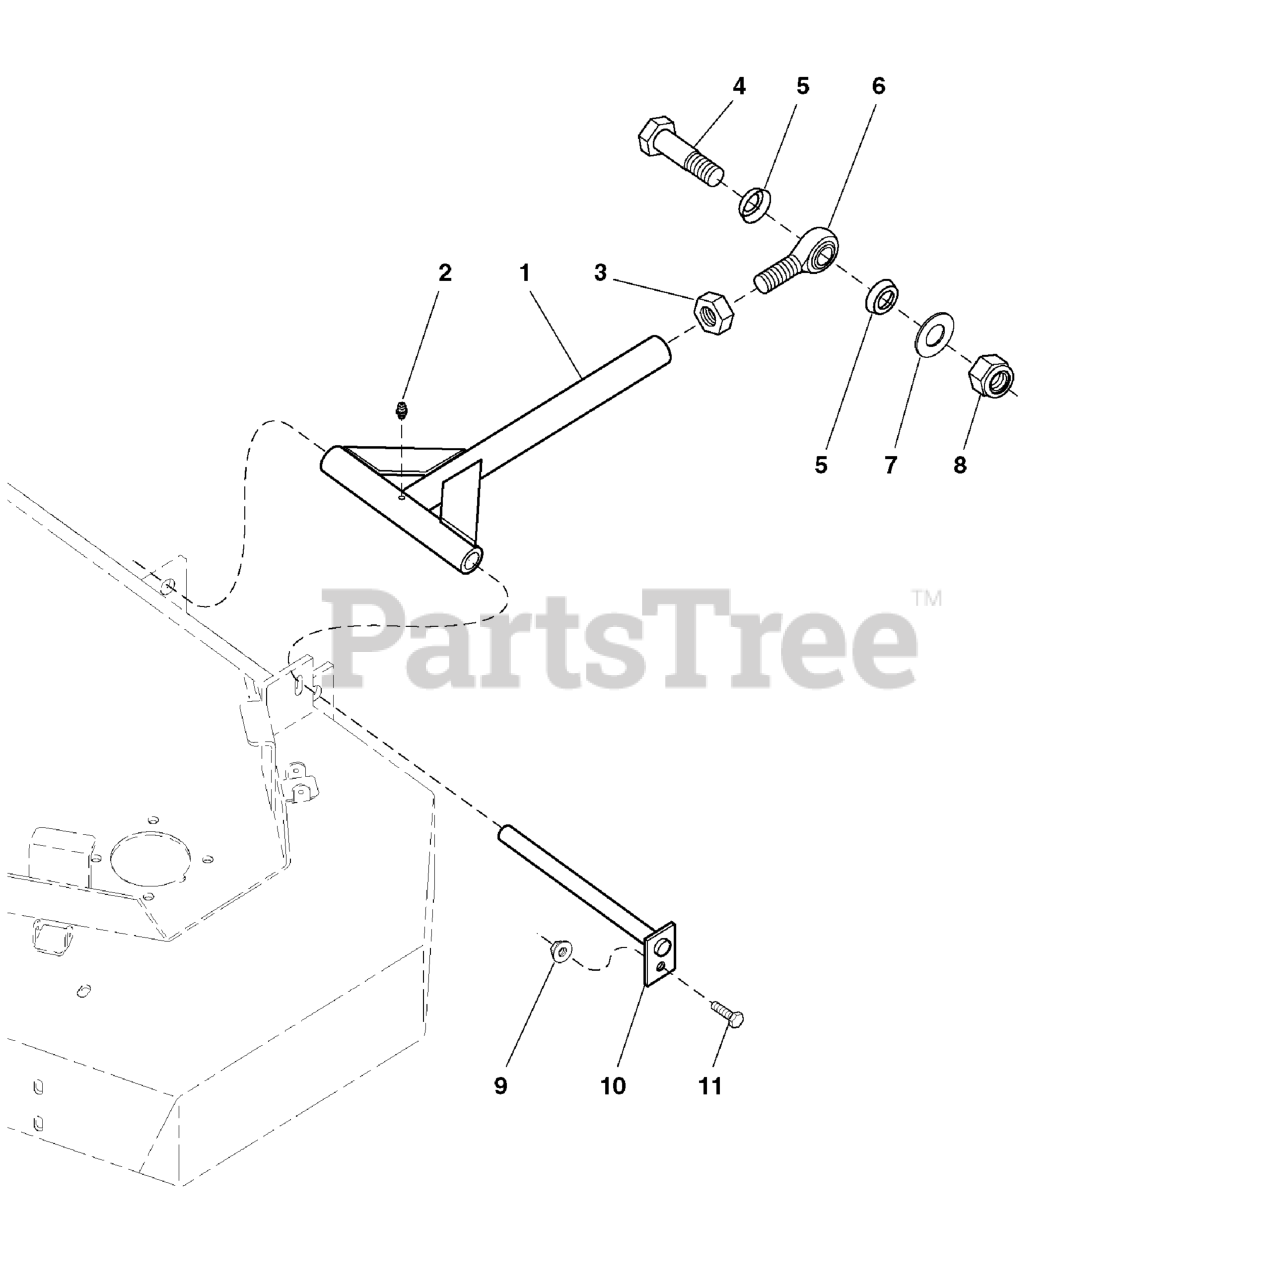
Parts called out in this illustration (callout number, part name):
1	ASSM, DECK PUSHER BAR
2	GREASE FITTING
3	NUT, 3/4-16 Hex Jam
4	BOLT, 3/4-16 x 3
5	ROD END SEAL
6	BALL JOINT, 3/4-16 Male
7	WASHER, 3/4 SAE
8	NUT, 3/4-16 Hex Nylon Lock
9	NUT, 5/16-18 HEX SERRATED FLANGE (LARGE)
11	BOLT, 5/16-18 X 1 GD5 YZ
